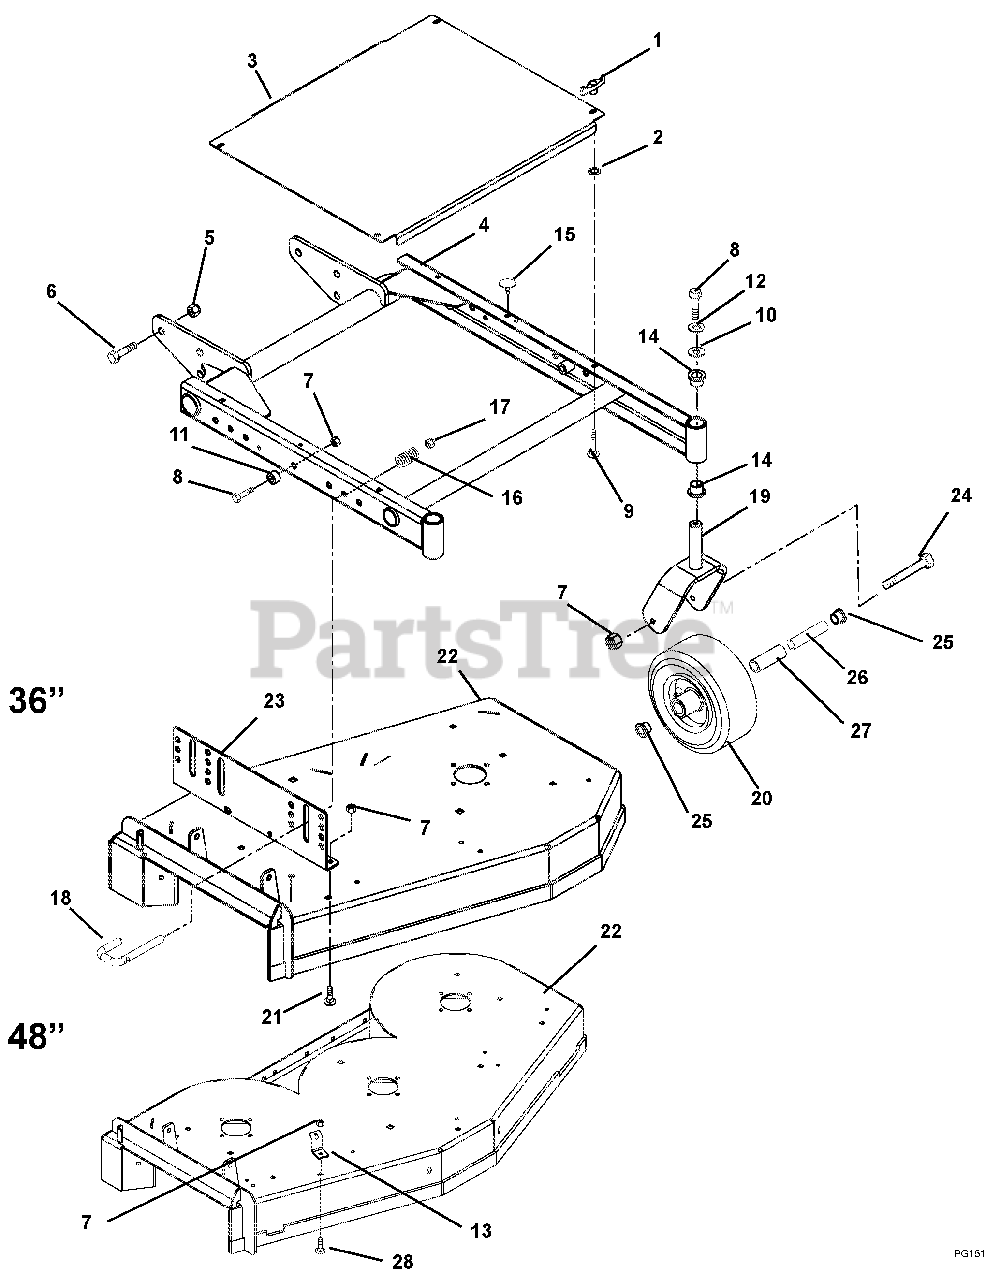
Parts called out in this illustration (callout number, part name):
1	Knob- Wing .312-18 (105, 120, 123, 124)
2	Nut-Push .312 (105, 120, 123, 124)
3	Cover, Belt Pro Mower (105, 120)
4	Weldment - Mower Frame 36" (105, 120)
5	Nut-Locking-Nylon .625-11
6	Bolt-Hex .62-11 x 1.50
7	Nut-Locking-Top-Flange .38-16 (105, 120)
8	Bolt-Hex .38-16 x 1.25 Grade 5
9	Bolt-Round Head Square Neck .31-18 x 1.00 (105, 120, 123, 124)
10	Washer-Flat-Steel .38 x 1.50 x .125
12	Washer-Locking .38 x .094 Regular
13	Anchor, Spring
14	Bushing-Flange 1.00 x 1.25 x 1.50 x 1.50
15	Bumper Grommet .125 x .25 Dia.
16	Spring-Compression .058 x .65 x 2.13
17	Nut-Locking-Center .50-13
18	Pin- Latch
19	Weldment-Caster Fork
20	Wheel 9 x 3.50
21	Bolt-Round Head Square Neck .38-16 x 1.00 Grade 5 (105, 120, 123, 124)
22	Kit, 32" Fixed Mower Deck with Decals
23	Kit-Mower Side Support Bracket-Right Hand and Left Hand
24	Bolt-Hex .38-16 x 5.50
25	Bearing-Retainer
26	Bearing .625 x .380 x 4.08
27	Bearing-Roller
28	Bolt-Round Head Square Neck .38-16 x .75 Grade 5
